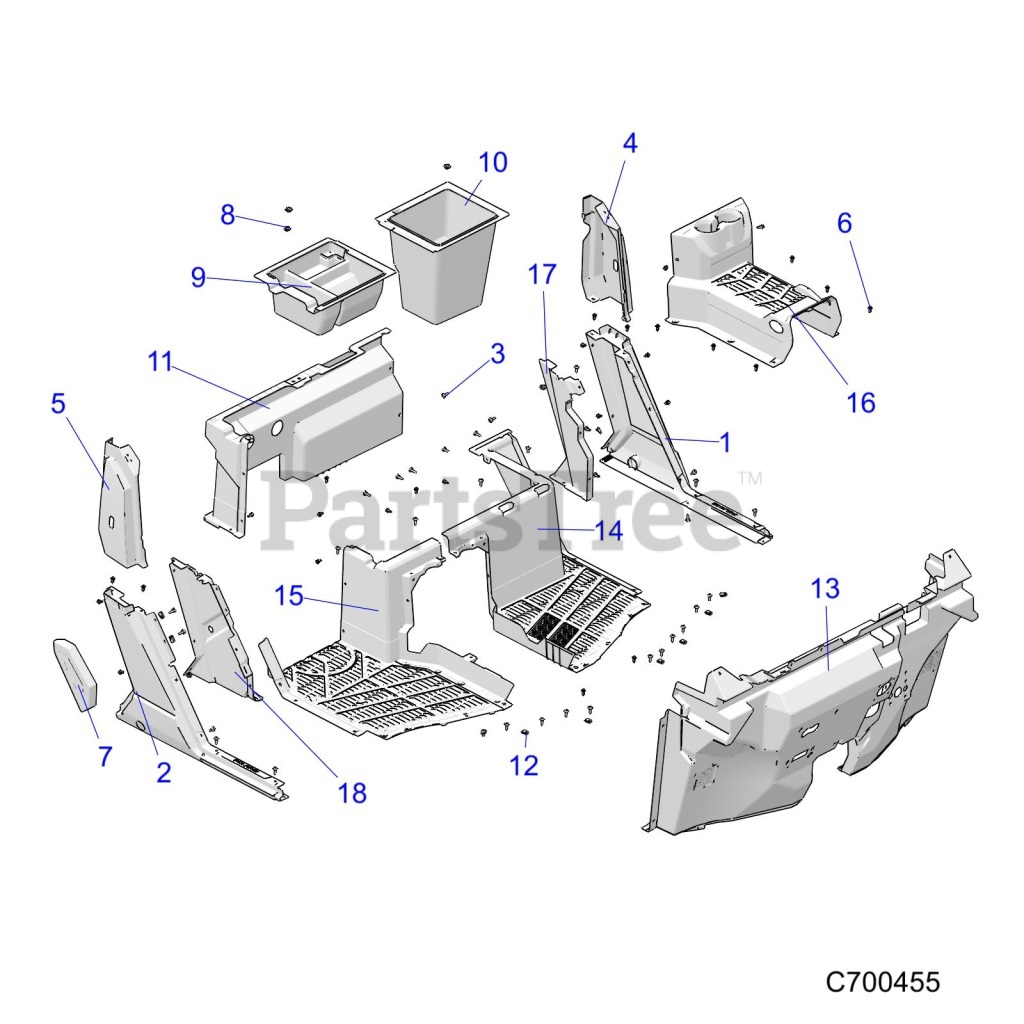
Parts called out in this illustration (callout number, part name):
1	COVER-ROCKER,CREW,LH,BLK
2	COVER-ROCKER,CREW,RH,BLK
3	SCR-TXTH-M6X1.0X25 RIE
4	COVER-ROPS PILLAR,LH,BLK
5	COVER-ROPS PILLAR,RH,BLK
6	RIVET-TUFLOK,.315-.325X.787 (5
7	COVER-SEAT PIVOT,BLK
8	PLUG-COMPARTMENT
9	STORAGE, UNDERSEAT, CNTR, BLK
10	STORAGE, UNDERSEAT, FRT, LH, BLK
11	COVER-REAR CLOSE OFF,BLK
12	NUT-M6-1.0,U-TYPE (2.5-3.8)
13	FLOOR-CLOSEOFF,UPPER,SPLY,BLK
14	FLOOR,LH,BLK
15	FLOOR,RH,BLK
16	COVER-TUNNEL FLOOR,BLK
17	COVER-INNER ROCKER, LH, BLK
18	COVER-INNER ROCKER, RH, BLK
